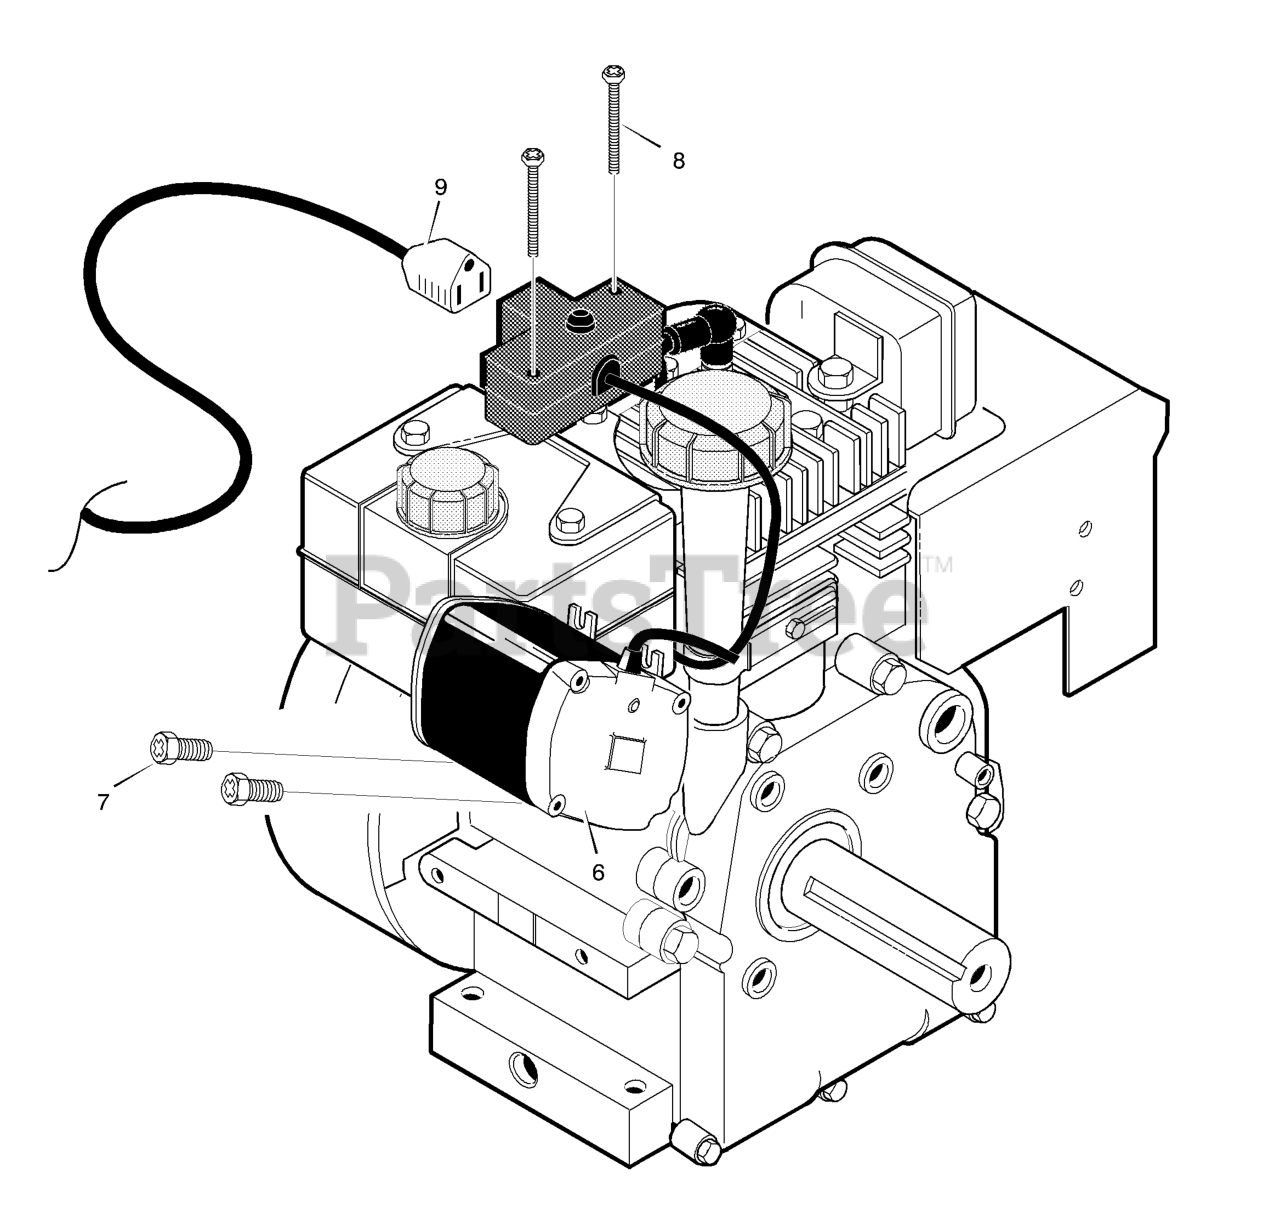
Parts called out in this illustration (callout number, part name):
6	MOTOR, STARTER
8	SCREW
9	CORD, STARTER
